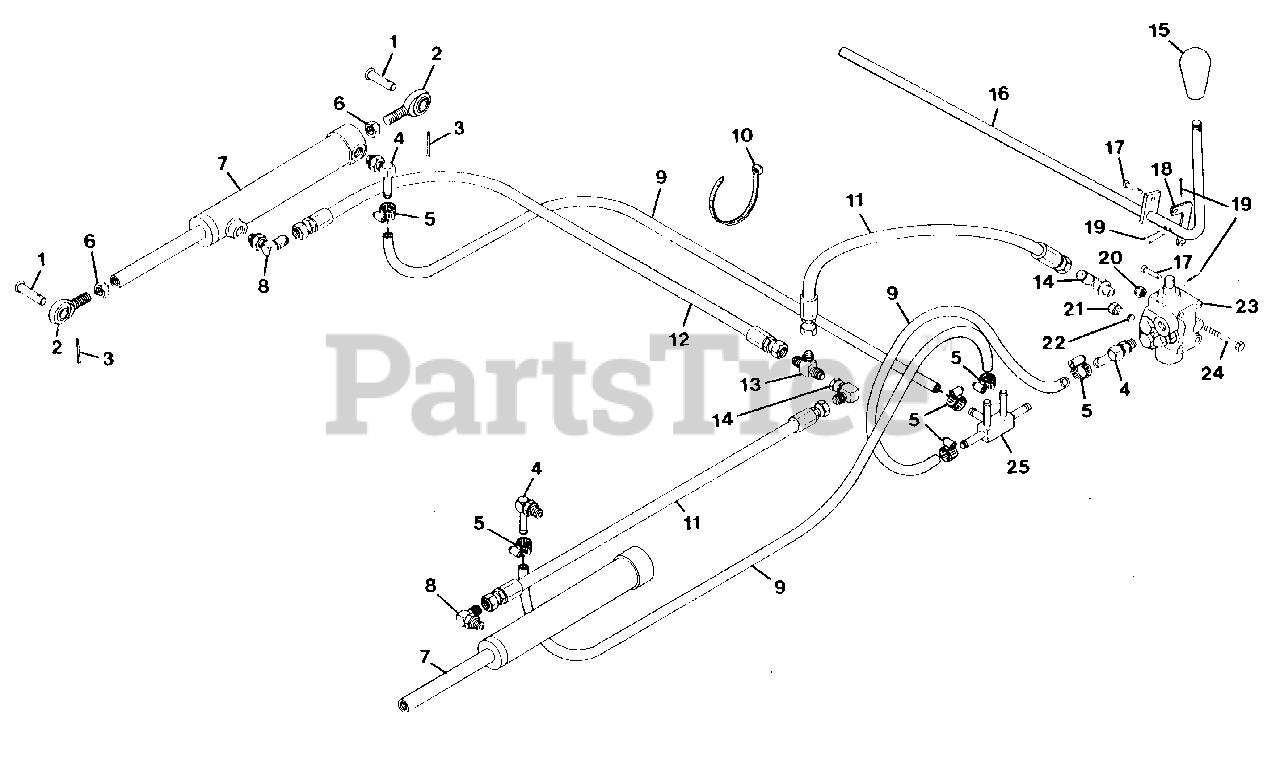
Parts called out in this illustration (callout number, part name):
1	Pin, Clevis .50x1.330
2	Assembly, Rod End R.H.
3	Pin, Cotter .125x1.25
4	Adapter, 4601-6-6
5	Clamp, Hose
6	Nut, Jam 1/2-20
7	Cylinder, Steering
8	Adapter, PH 2503-6-6
9	Hydraulic Hose,
10	Tie Wrap, Black
11	Assembly, Hydraulic Hose
12	Assembly, Hydraulic Hose
13	Adapter Tee
14	Adapter, PH # 3903-6-6
15	Knob, PTO
16	Weldment, Lift Lever
17	Pin, Clevis
18	Rod, Hydraulic Control
19	Pin, Cotter .094x.75
20	Nut, Lock 1/4-20
21	Plug, PH 05PO-4
22	Plate, Flow Restriction
23	Valve, Hydraulic
24	Bolt, Hex 1/4-20x2.75
25	Manifold
